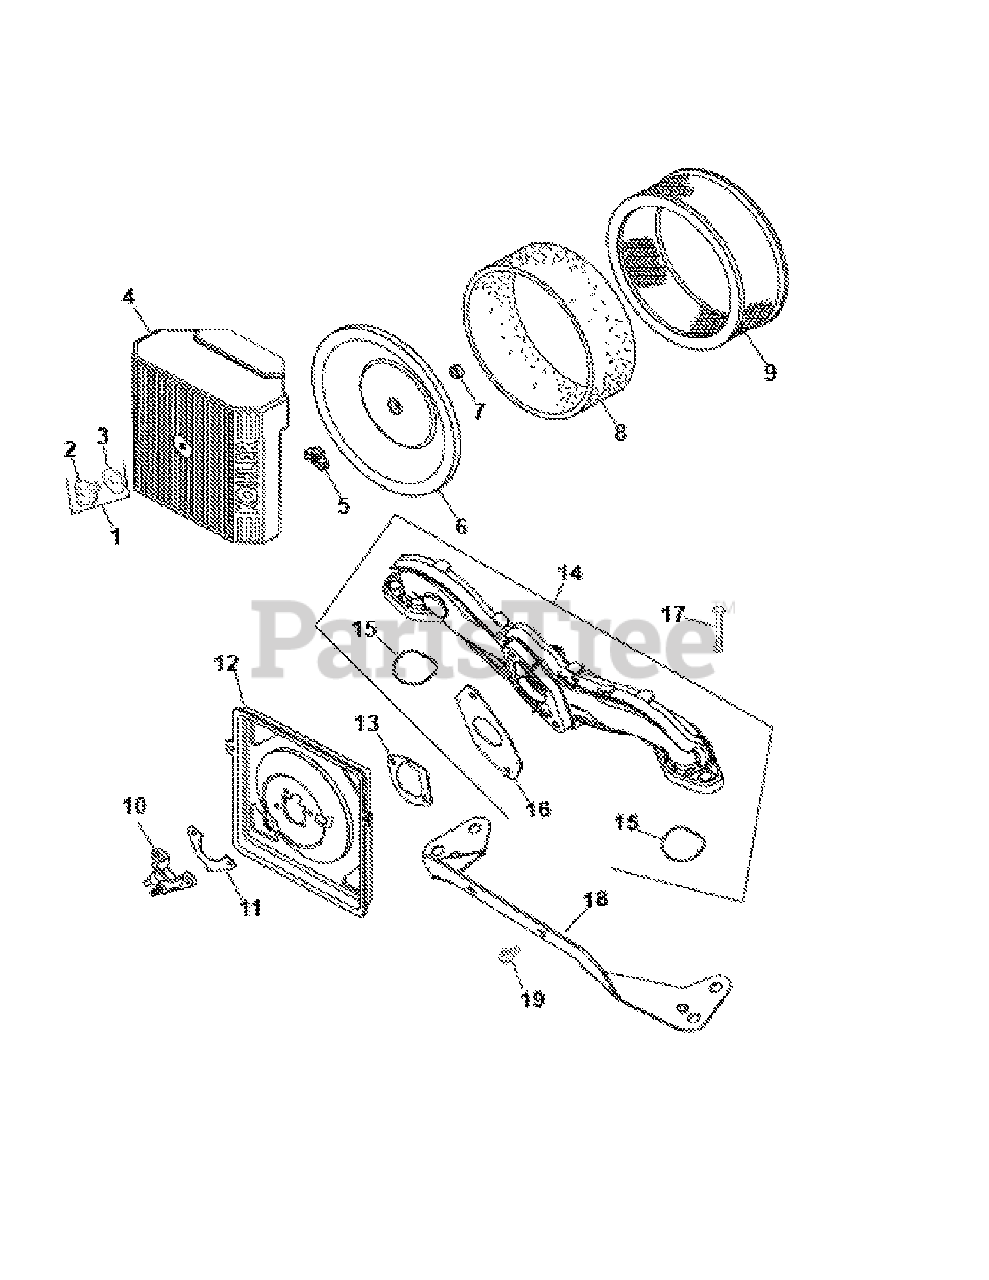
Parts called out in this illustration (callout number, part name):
1	Knob With Seal Kit
4	Air Cleaner Cover
6	Inner Air Cleaner Cover
7	Inner Air Cleaner Seal
8	Precleaner Element
9	Air Cleaner & Precleaner Elements
10	Spit Back Cup w/Stud
11	Spit Back Cup Gasket
12	Air Cleaner Base
13	Air Cleaner Gasket
14	Intake Manifold
15	Intake Port O-Ring
16	Carburetor Gasket
17	Hex Flange Screw (M6 x 1.0 x 40)
18	Air Cleaner Bracket
19	Hex Flange Screw (M5 x .8 x 10)
